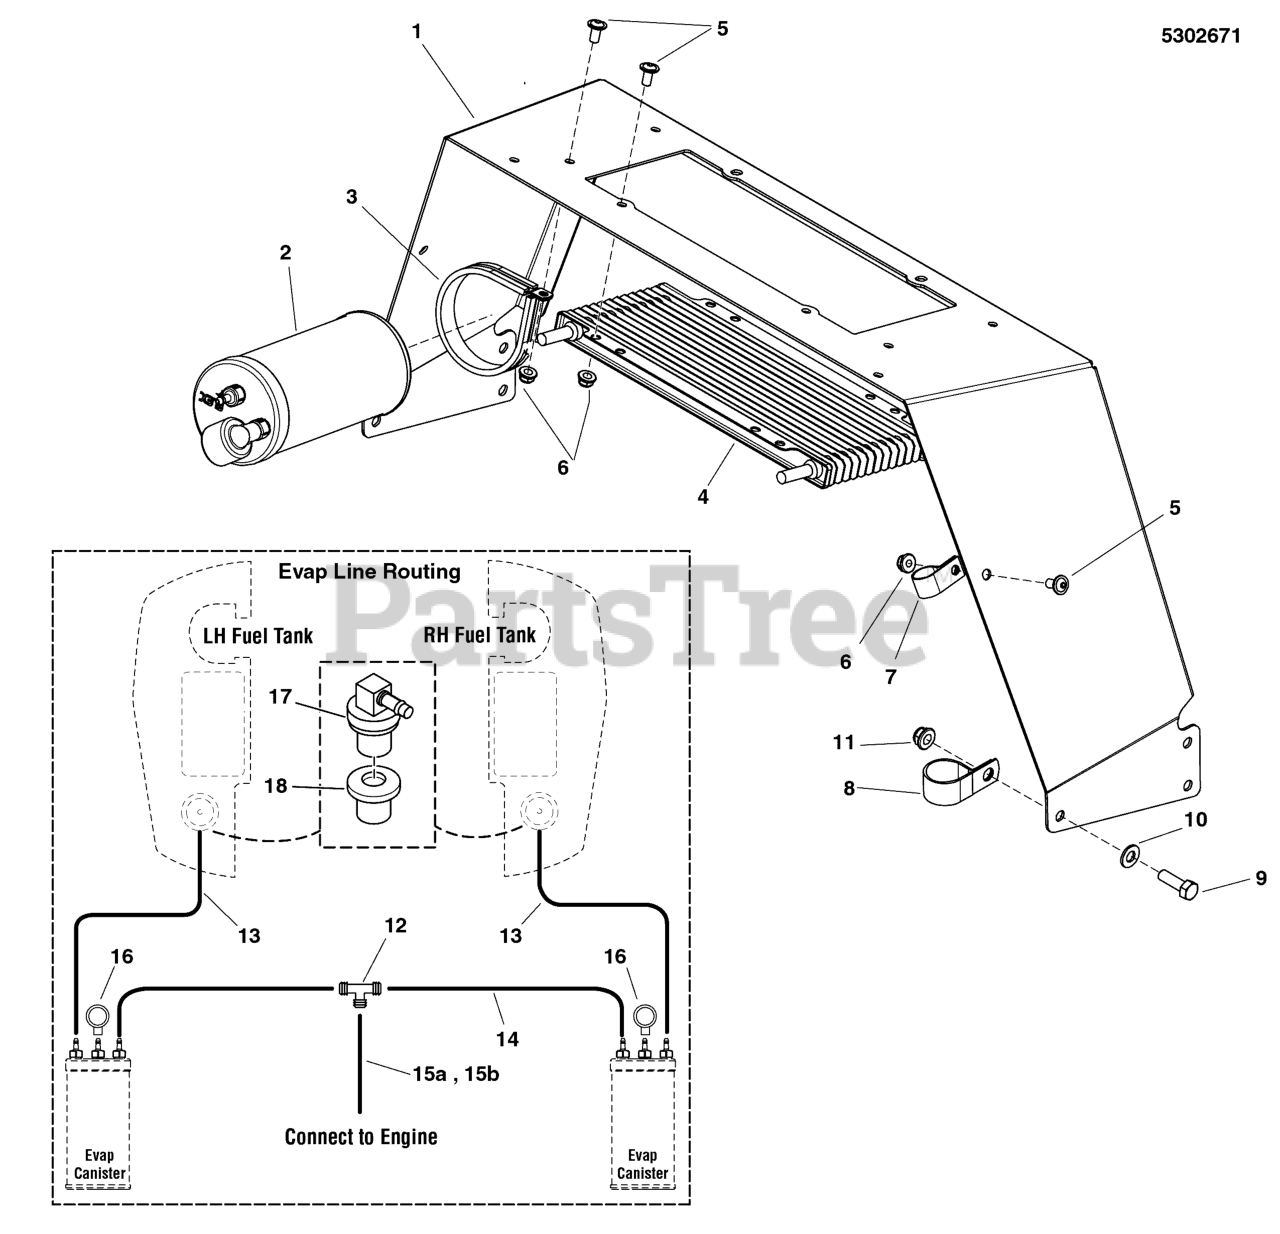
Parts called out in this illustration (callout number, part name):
1	MOUNT, OIL COOLER/CARB CANISTER - BLK
2	CNSTR, CARB, 6 GAL
3	CLAMP, 3" ID, CUSHIONED, STAINLESS
4	OIL COOLER, .75 X 11.0 X 24 PLATES
5	SCREW, 1/4-20 X 1/2 ALLEN BH
6	NUT, 1/4-20 HEX NYLOCK FLANGE
7	CLAMP, VINYL COATED, 5/8 ID
8	CLAMP, HOSE, 1.000 DIA.
9	BOLT, 5/16-18 X 1 GD5 YZ
10	WASHER, 5/16" SAE
11	NUT, 5/16-18 HEX NYLOCK FLANGE
12	FITTING, 3/16" TEE, BARB TYPE, HDPE
13	HOSE, VAPOR, 5MM ID, 16.00 LG
14	HOSE, VAPOR, 5MM ID, 38.00 LG
16	DUST FILTER, CANISTER (SV)
17	REMOTE VENT ASSEMBLY
18	GROMMET
